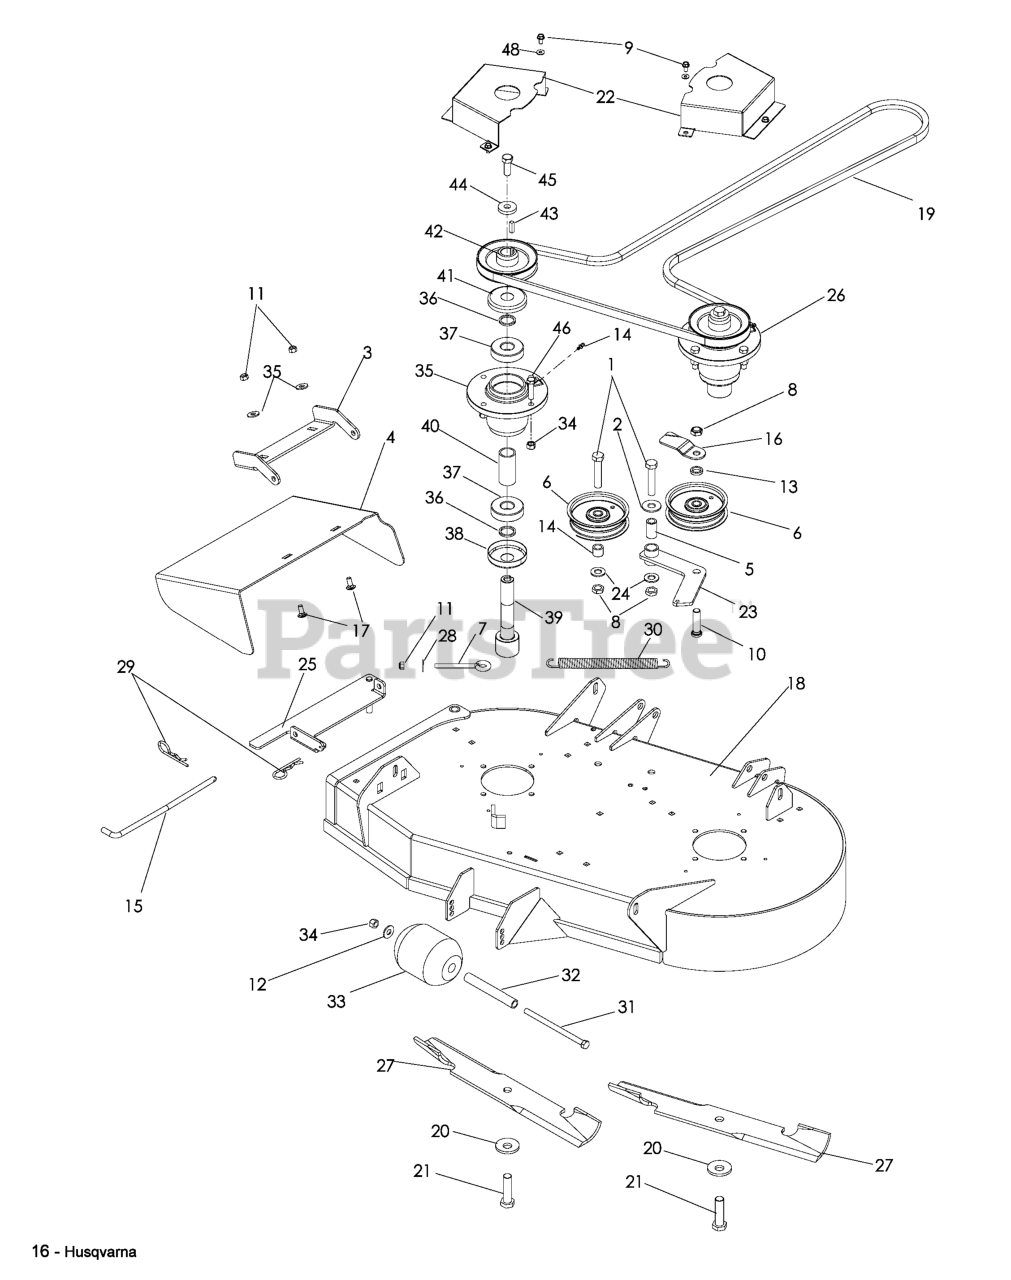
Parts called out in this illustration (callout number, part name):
1	HEX SCREW 1/2-13 X 2.5" GR 5
2	WASH USS FLAT 1/2
3	HINGE, 34-44, ORANGE
4	CHUTE, 34 ORANGE
5	BUSHING DIXON 1080
6	PULLEY IDLER
7	EYE BOLT 5/16 X 3.50
8	NUT, 1/2-13 THIN PROF NYL
9	SCREW 1/4 X 5/8
10	STUD 1/2-13 X 2
11	NUT 5/16 NYLOC
12	WASHER 3/8 FLAT
13	HD PULLEY SPACER
15	DEFLECTOR PIN
16	BELT GUARD BLK
17	BOLT 5/16C X 3/4" CARRIAGE
18	DECK, EZF, W/DECALS 34"
20	BLADE WASHER
21	BLADE BOLT
22	PULLEY GUARD 34
23	IDLER ARM WLDT., BLACK
24	WASHER 1/2" FLAT
25	MOUNT, DEFLECTOR, ORANGE
26	SPINDLE ASM.
27	BLD 34 HI-LIFT FUSION
28	FLAT WASHER 5/16 SAE
29	STAINLESS COTTER
30	SPRING, DECK BELT
31	BOLT 3/8 X 6 GR5
33	ROLLER 3-3/4 DIA. X 4-1
34	NUT 3/8-16 NYLOC
35	DECK HUB MACHINED
36	HUB PULLEY SPACER
37	BEARING - 6305 - 2RS
38	TRASH GUARD
39	SHAFT SPINDLE
41	TRASH GUARD
43	KEY - 1/4 X .88
44	WASHER .525 X 1.375 X .25
45	1/2-20 UNF X 1 1/4 HHBLT
46	HCS 3/8C X 1 1/2
47	ZERK, 3/16, DRIVE IN
48	WASHER 1/4 FLAT
